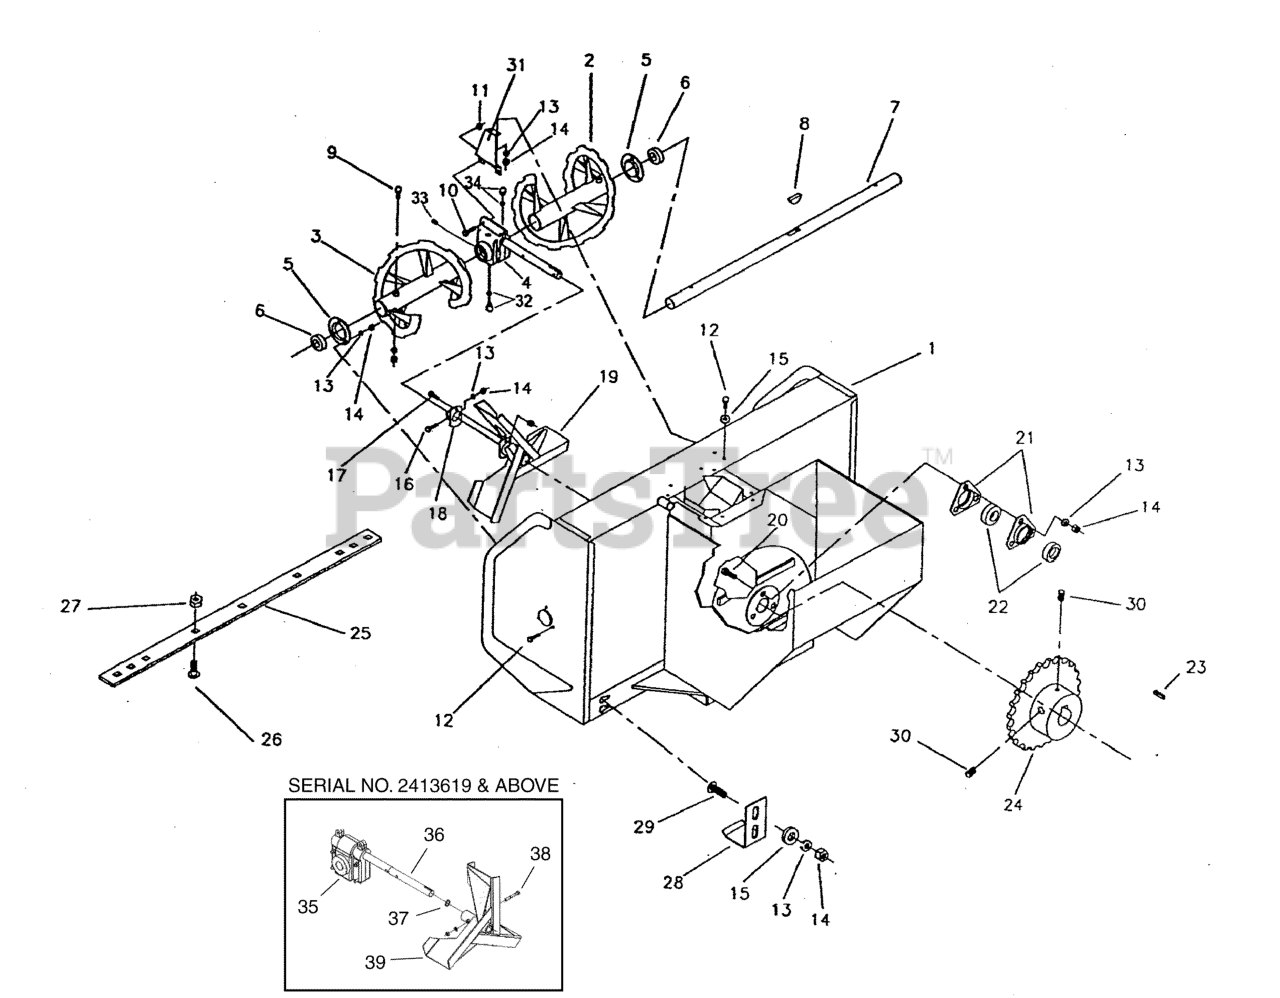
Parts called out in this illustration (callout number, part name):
2	Auger R.H.
3	AUGER R.H. SNOWBLOWER
3	Auger L.H.
4	Worm Gear
4	Seal Kit
5	Bearing Flange
6	Bearing With Locking Collar
7	Output Shaft
8	Key Woodruff
9	Shear bolt 5/16" NC x 2 1/4" w/ lock & nut, silver PTD, gr5
11	Nylon Lock Nut
14	Hex Nut 5/16" NC
15	Flat Washer 3/8" Diameter Hole
17	Shear Bolt 1/4" NC x 1-1/4" With Stover Nut
18	Fan Adaptor Shear Plate
19	Fan Assembly
21	Bearing Flange
22	Bearing With Locking Collar
23	Key 1/4" x 1/4" x 1"
24	Sprocket 40B28
25	Cutting Edge
27	Stover Nut 5/16" NC
28	SKID SHOE
31	Worm Gear Support
32	Plug 1/8" NPT
33	Plug 1/8" NPT
34	Pressure Plug 1/8" NPT
35	Worm Gear
36	Driving Shaft
37	Snap Ring - External
38	Shear Bolt, Lock Washer & Nut
39	Fan Assembly
